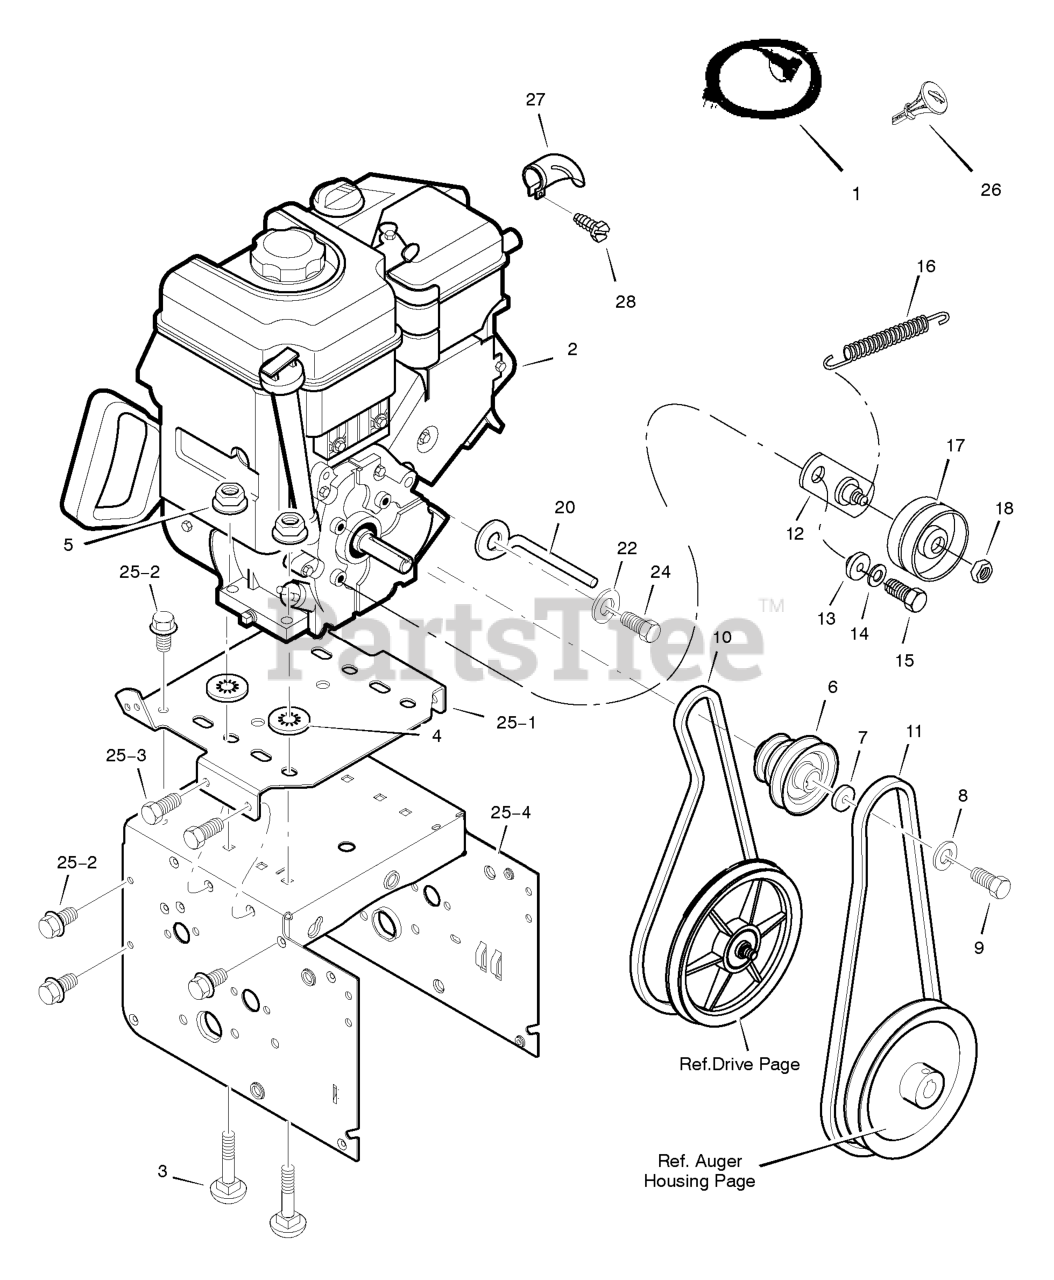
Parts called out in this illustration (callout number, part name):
1	CORD, Electric, 10FT. 110V
2	ENGINE
3	BOLT, CARRIAGE
4	RETAINER, PUSH
6	PULLEY, ENGINE
8	WASHER
10	BELT, DRIVE V 4L
11	BELT, AUGER V 3L
12	BRACKET ASSEMBLY, IDLER
13	BUSHING, IDLER BRACKET
14	WASHER, SPLIT
15	SCREW 5/16-24 X 0.75
16	SPRING, IDLER TRACTION DRIVE
17	PULLEY, IDLER
18	NUT, JAM 3/8-16
20	GUIDE, ROD BELT
22	WASHER
25	FRAME ASSEMBLY
25-1	PLATE, ENGINE
25-2	SCREW
25-4	MOTOR BOX
26	KEY, BRIGGS ENGINE
27	DEFLECTOR, Muffler
